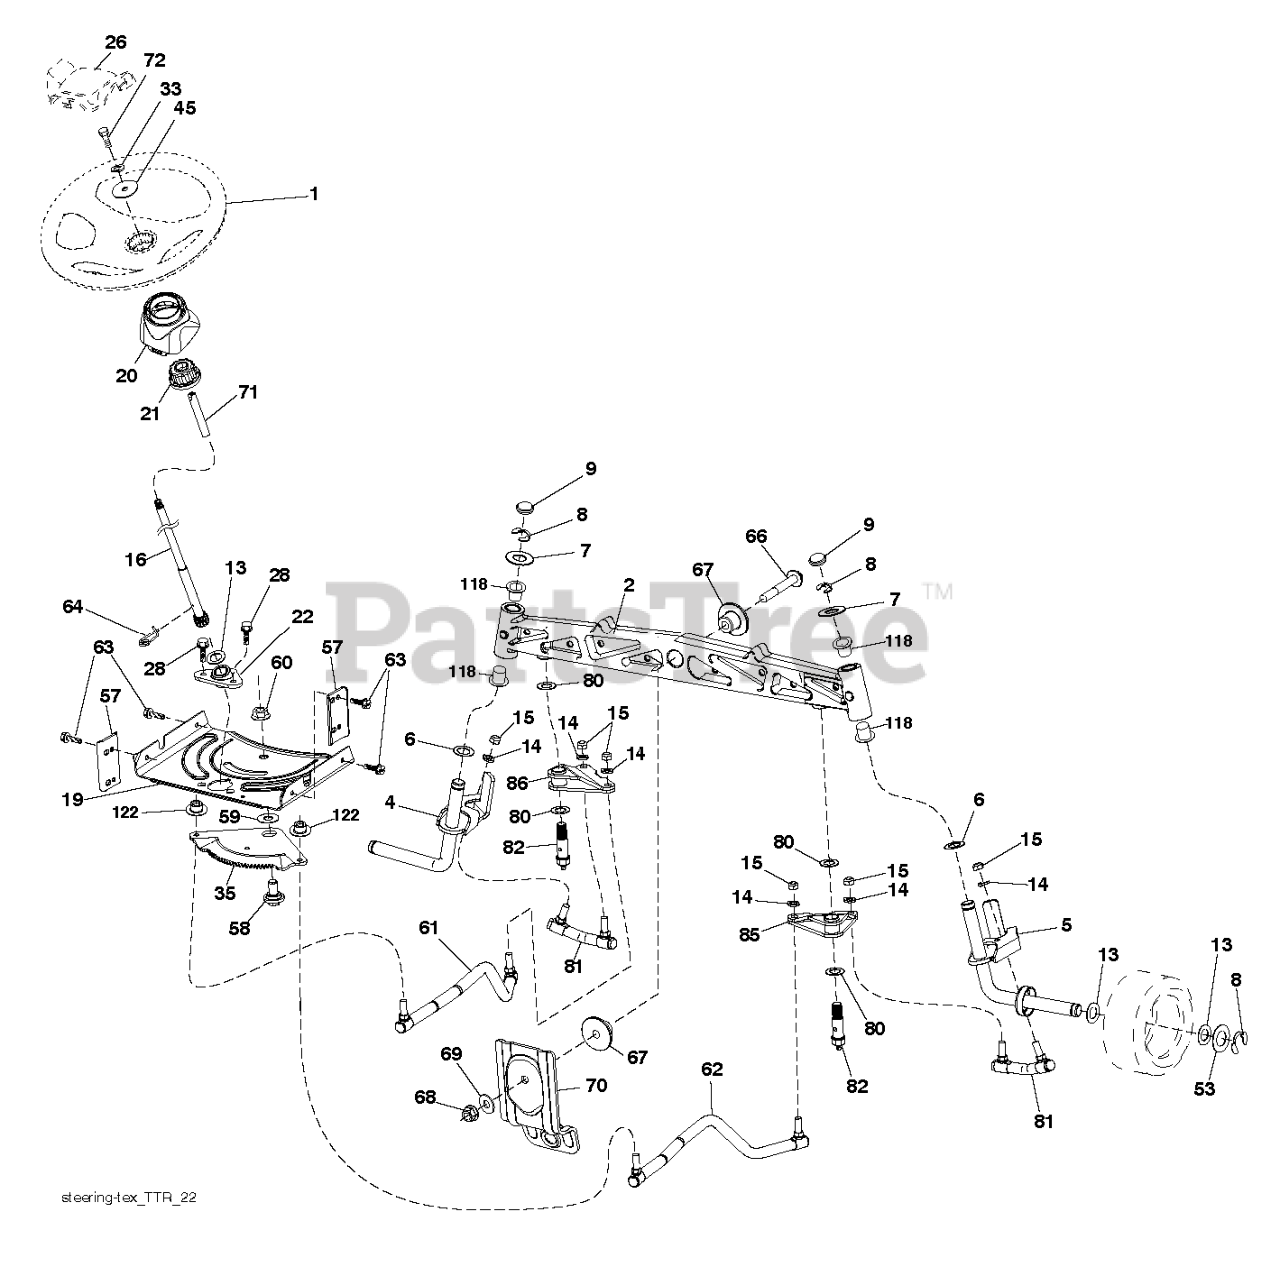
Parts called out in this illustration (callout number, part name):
1	WHEEL.STEER.HUSQ.SR.498.OVMLD
2	RP SUBASM.AXLE.CAST.NZTR.
4	SPINDLE WELDMENT.SPINDLE.LH.15
5	SPINDLE WELDMENT.SPINDLE.RH.15
6	THRUST WASHER
9	CAP.SPINDLE.BLACK
14	WASHER, LOCK 3/8
15	NUT CROWNLOCK 3/8-24
16	SHAFT SHAFT.STEERING/HIGH3PLAT
19	PLATE.STEER.DDL.NLT/NG
20	STEERING.BOOT.HUSQ.LT
21	STEERING.WHEEL.ADAPTER
22	BUSHING.ASM.STEERING.A
26	INSERT.CAP.WHL.STRG.HUSQ.PREM
28	SCREW, 3/8-16X3/4
33	WASHER.LOCK.HVY.HLCL.SPR.5/16
35	GEAR GEAR.SECTOR.TEX.NZTR
45	WASHER.11/32
53	WASHER.HARDENED
57	BRACKET.UPSTOP.TEX
58	BOLT.SHOULDER.SECTOR.P
59	WASHER.THURST.SECTOR.S
60	NUT FLANGE LOCK 5/8-11
61	LINK SUBASM.LINK.DRAG.LH.NZTR
62	TUBE TUBE
63	SCREW
64	RETAINER.CLIP.SPRING.S
66	BOLT HEX FGHD 7/16-14 X 3 SERR
67	BUSHING.PM.FRONT AXLE
68	NUT.LOCK.FLANGE.7/16
69	WASHER.1.5X.505X.118
70	BRKT.DECK.SUSPENSION.F
71	SHAFT.EXTEN.STRG.SPLINE
72	BOLT 5/16-18 X 4 W/PATCH
80	THRUST WASHER
81	LINK SUBASM.LINK.CROSS.NZTR
85	PIVOT SUBASM.PIVOT.RH.NZTR
86	PIVOT SUBASM.PIVOT.LH.NZTR
118	BUSHING, AXLE CAST
122	CAP.GEAR.SECTOR.TEX
